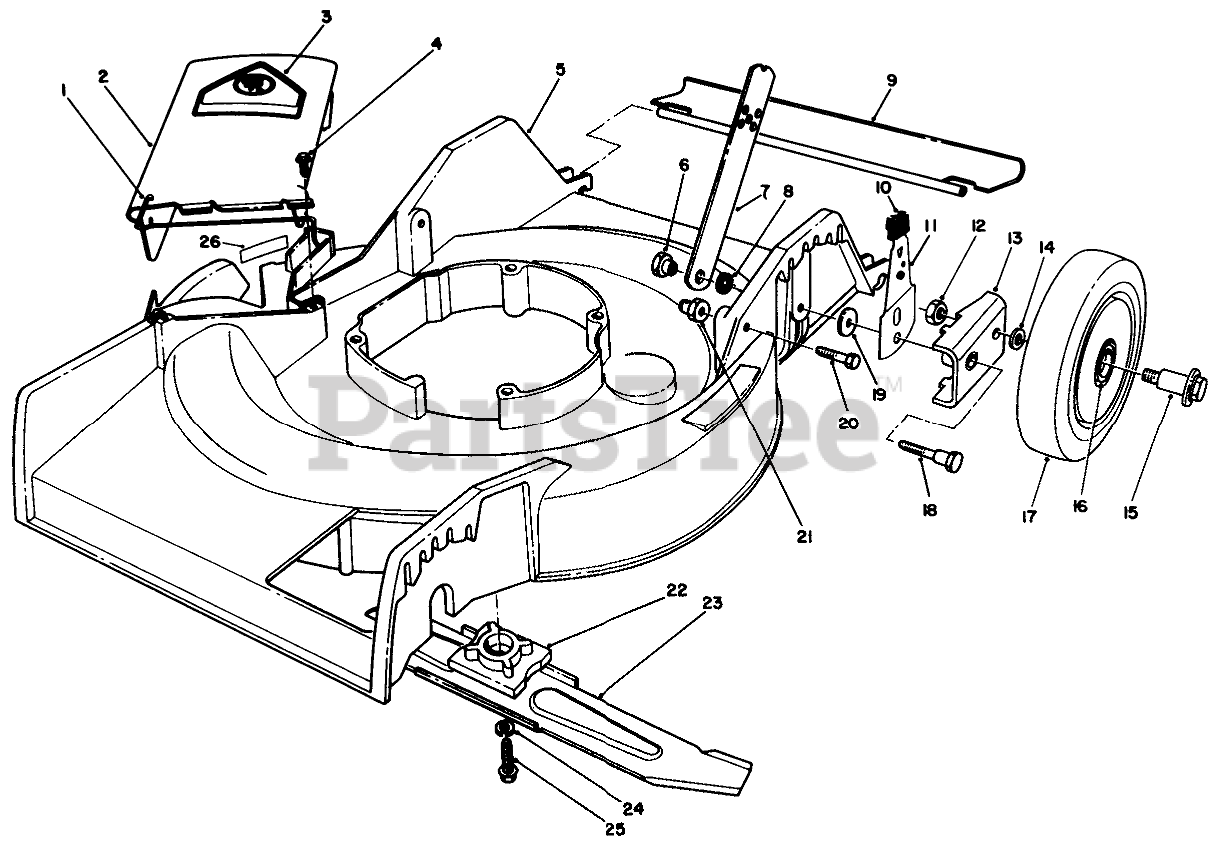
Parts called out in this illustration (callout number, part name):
1	SPRING HINGE
2	Deflector Assembly (Incl. Ref. #1 & 3)
3	DECAL-DANGER
4	SCREW-HWH
5	Housing-21" (Incl. Ref. #26)
6	HANDLE PIVOT NUT
7	HANDLE LATCH
8	SPACER
9	SHIELD - TRAILING
10	KNOB-ARM
11	SPRING ARM ASSEMBLY
12	Nut
13	HP PIVOT ARM ASM
14	WASHER
15	BOLT-WHEEL
16	BUSHING
17	Wheel & Tire Assembly (Incl. Ref. #16)
18	PIVOT SCREW
19	PIVOT WASHER
20	SCREW-HH
21	HANDLE PIVOT NUT
22	BLADE RETAINER
23	Blade
24	WASHER-LOCK
25	SCREW-HH
26	DANGER DECAL
